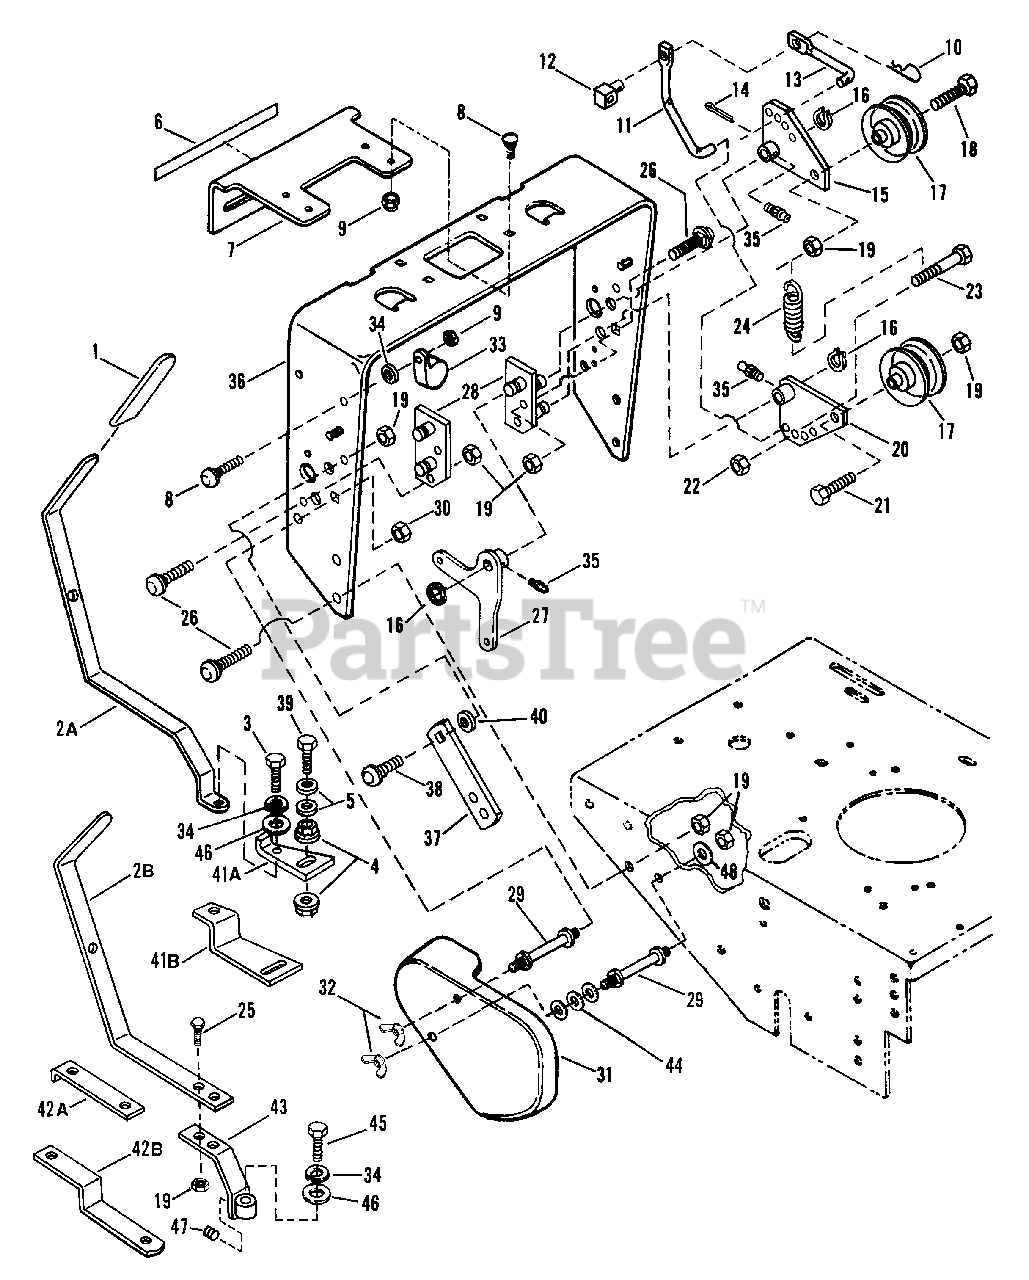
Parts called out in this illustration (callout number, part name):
1	GRIP, Shift Lever
2A	LEVER, Shifter
2B	LEVER, Shifter
3	SCREW, 1/4-28 x 5/8" Hex Cap
3	SCREW, 1/4-28 x 3/4" Hex Cap
4	NUT, 1/4-20 Hex Flange Lock
5	WASHER, 1/4" I.D., 1" O.D. Flat
6	DECAL, Shift
7	QUADRANT, Shift
8	SCREW, 1/4-20 x 3/4" Short Neck Carriage
9	NUT, 1/4-20 Hex, Nyloc
10	HAIR-PIN, 3/32 x 1 3/16"
11	LINK, Long (Left Hand)
12	SWIVEL
13	LINK, Short
14	COTTER-PIN, 3/32 x 1"
15	WELDMENT, Idler (Upper Left & Lower Right Sides)
16	RING, 5/8" External Retaining
17	PULLEY, Idler
18	SCREW, 3/8-16 x 2 1/2" Hex Head Cap
19	NUT, 3/8-16 HEX NYLON LOCK
20	WELDMENT, Idler (Lower Left & Upper Right Sides)
21	BOLT, 3/8-16 X 2, GD5, CZ
22	NUT, 5/16-18 Hex Flange Lock
23	BOLT, 5/16-18 X 3/4 GD5
24	SPRING, Extension
25	BOLT, 3/8-16 X 1" GD5 CZ
26	BOLT, 3/8-16 x 1" Carriage
27	WELDMENT, Blade Bellcrank
28	WELDMENT, Idler Pivot (Left Hand)
29	STUD, Fender Mount
30	NUT, 3/8-16 Hex Jam
31	FENDER, Left Hand
32	WING-NUT, 3/8-16
33	MODULE
34	WASHER, 1/4 Internal Tooth Lock
35	FITTING, Lube
36	BRACKET, Tank
37	ARM, Brake
38	BOLT, 3/8-16 x 3/4" Short Neck Carriage
39	BOLT, 1/4-20 X 1" GD5 CZ
40	WASHER, 3/8" Flat
41A	ARM, Reverse
41B	ARM, Reverse
42A	LEVER, Reverse
42B	LEVER, Reverse
43	WELDMENT, Shifter Lever
44	WASHER, 3/8" USS
45	CAPSCREW-HEX HD 5/16-18X0.500 G5 BLK
46	WASHER, 1/4 Flat
47	SCREW, 1/4-20 x 5/16" Socket Set
48	WASHER, 1/2 Flat
